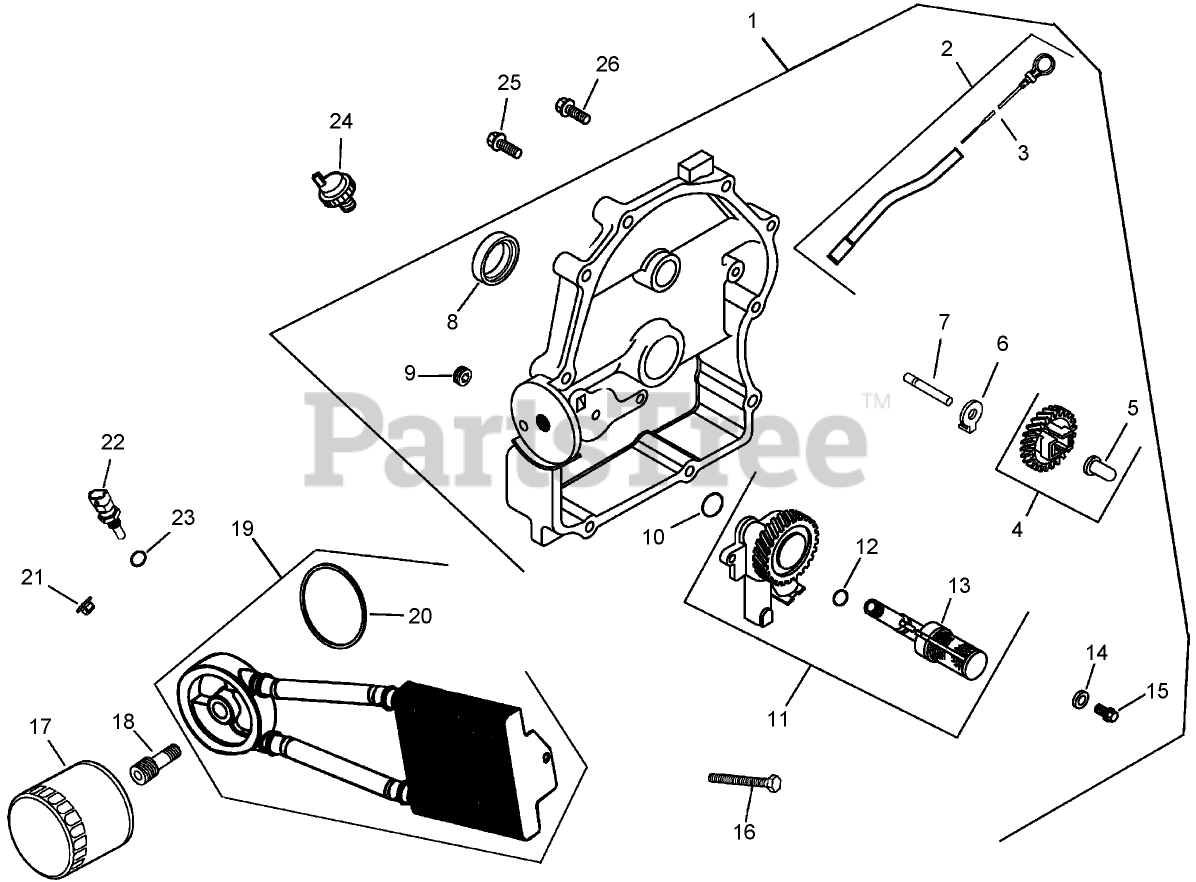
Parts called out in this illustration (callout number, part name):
1	Closure Plate ASM (Includes 2-15)
2	Dipstick Tube ASM (Includes 3)
3	Dipstick
4	Governor Gear Kit (Includes 5)
5	PIN-REGULATING, GOVERNOR
6	TAB-LOCKING
7	SHAFT-GEAR, GOVERNOR
8	SEAL-OIL (P-T-O END)
9	PLUG-PIPE, COUNTERSUNK (1/8)
10	O-Ring
11	Oil Pump ASM (Includes 12, 13)
12	O-RING
13	TUBE-PICK UP, OIL
14	WASHER-FLAT (6 MM)
15	SCREW-FLANGE, THREAD FORMING (M6X1.0X25)
16	SCREW-TAPPING
17	FILTER-OIL
18	NIPPLE-FILTER, OIL
19	Cooler-Oil (Includes 20)
20	O-RING
21	Nut-Plastic
22	Sensor-Temperature
23	O Ring-Oil Pick-up
24	SWITCH-PRESSURE, OIL
25	Screw-HF (M8x1.25x45)
26	SCREW-FLANGE (M8X1.25X45)
